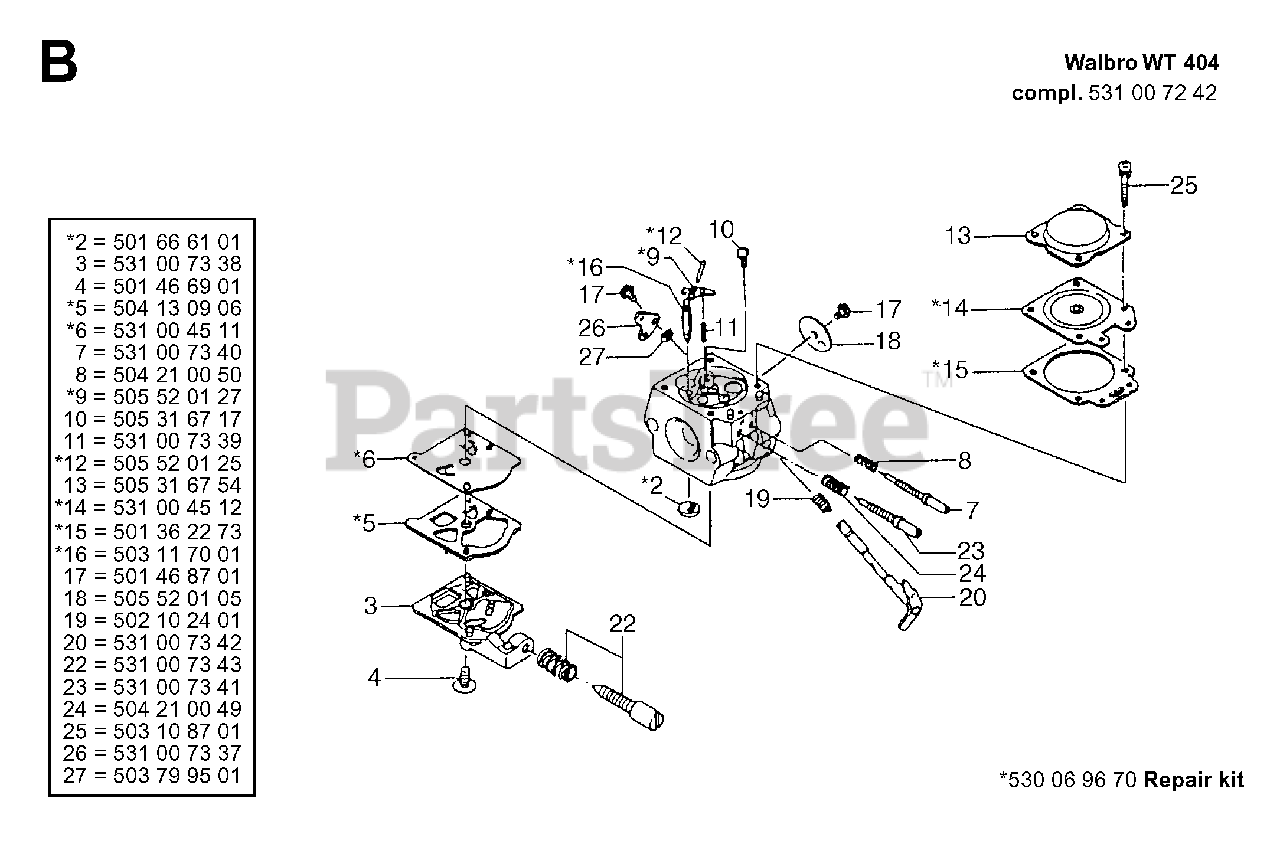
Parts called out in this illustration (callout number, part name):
2	FUEL INLET SCREEN
5	GASKET
7	NEEDLE HIGH SPEED
8	SPRING/COMPRESSION
9	LEVER
12	FULCRUM PIN
13	DIAPHRAGM COVER
15	GASKET
16	VALVE/INLET.
18	THROTTLE FLAP
19	SPRING, CARB. 40
20	THROTTLE SHAFT
22	IDLE SCREW
23	LOW SPEED NEEDLE
24	SPRING, H-NEEDLE
25	SCREW W/ WASHER
